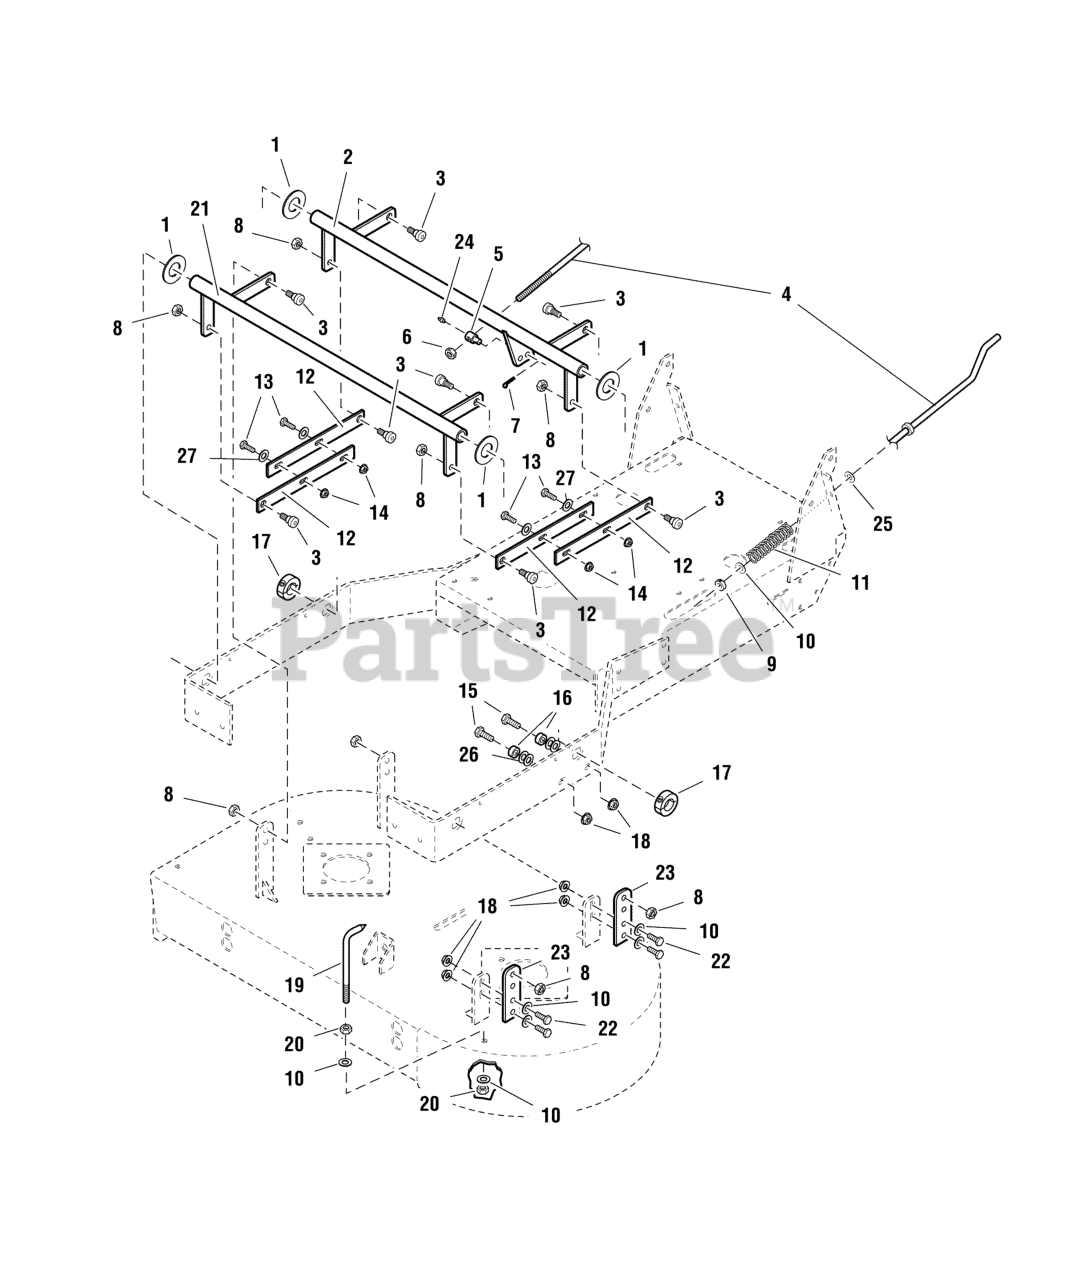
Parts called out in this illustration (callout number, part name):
1	WASHER-1.00 HYDRO CUT
2	WELD, DECK PIVOT, REAR
3	BOLT, 3/8-16 X 3/8", 1/2" SHOULDER
4	ROD CUTTER DECK HEIGHT CONTROL
5	LINKAGE, ADJUSTER
6	NUT, 3/8-16 HEX NYLON LOCK
7	PIN, 3/32 X 0.750, COT, ZINC/CLEAR
8	NUT, 3/8-16, HEX TOP LOCK
9	COLLAR, 3/8" SET
10	WASHER, 3/8 SAE
11	SPRING, REVERSE RETURN
12	LINK, DECK ADJUST.
13	BOLT, 5/16-18 X 1" GD5 YZ
14	NUT, 5/16-18 HEX SERRATED FLANGE (LARGE)
15	BOLT, 3/8-16 X 1-1/4" GD5 CZ
16	SPACER, .39 X .75 X .38
17	COLLAR, 1" DOUBLE SPLIT
18	NUT, 3/8-16 HEX NYLOCK FLANGE
19	POINTER, CUT HEIGHT
20	NUT, 3/8-16 HEX
21	WELD, DECK PIVOT, FRONT
22	BOLT, 3/8-16 X 1" GD5 CZ
24	GREASE FITTING
25	WASHER, 3/8" NYLON HYDRO CUT
26	WASHER, 3/8" GD.9 FLAT
27	WASHER, 5/16" SAE
